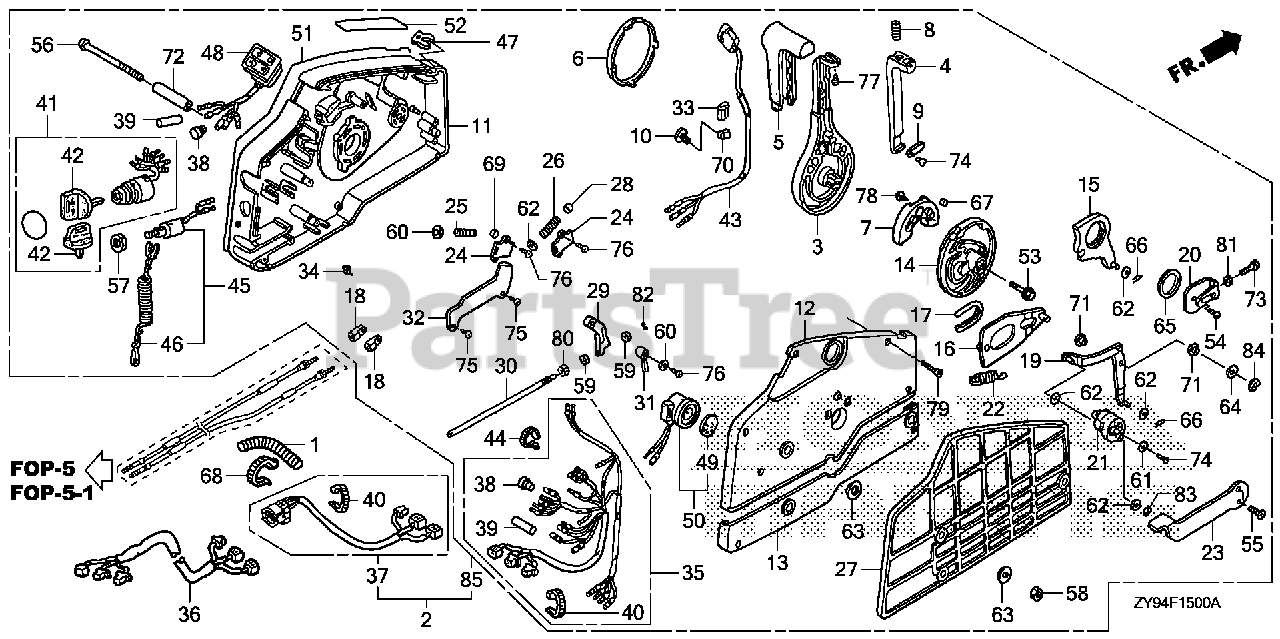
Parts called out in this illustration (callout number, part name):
1	TUBE, CORRUGATED (28MM)
2	BOX ASSY., REMOTE CONTROL (NHK MEC)
3	HANDLE, REMOTE CONTROL
4	LEVER, HANDLE LOCK
5	GRIP, REMOTE CONTROL HANDLE
6	CAP, HANDLE
7	BLOCK, NEUTRAL LOCK
8	SPRING, REMOTE CONTROL HANDLE
9	PLATE, LEVER SETTING
10	CLAMP, HARNESS
11	HOUSING, REMOTE CONTROL BOX (A)
12	HOUSING, REMOTE CONTROL BOX (B)
13	HOUSING, REMOTE CONTROL BOX (C )
14	WHEEL, CONTROL
15	ARM, SHIFT LINK
16	PLATE, SLIDING
17	COLLAR, SLIDING PLATE
18	PIVOT, SHIFT
19	ARM, LINK JOINT
20	BRACKET, LINK JOINT
21	WHEEL, ACCELERATOR
22	SPRING, ACCELERATOR WHEEL
23	LEVER, IDLE
24	PLATE, SPRING SETTING
25	SPRING, SHIFT CLICK
26	SPRING, CHOKE RETURN
27	SPACER, REMOTE CONTROL BOX
28	SPACER, CLICK SPRING
29	BLOCK, THROTTLE FRICTION
30	BOLT, FRICTION
31	SPACER, NEUTRAL SWITCH
32	CLAMP, POWER TILT CORD
33	PIPE, HARNESS GUIDE
34	SPACER, CABLE CLAMP
35	CABLE ASSY., REMOTE CONTROL (B) Use from Frame SN 1300029.
35	CABLE ASSY., REMOTE CONTROL (B) (FOR 4-LED)
36	CABLE ASSY., REMOTE CONTROL EXTENSION Use from Frame SN 1300029.
37	CABLE ASSY., SWITCH PANEL
37	CABLE ASSY., SWITCH PANEL (20FT) (NHK MEC)
37	CABLE ASSY., SWITCH PANEL (25FT) (NHK MEC)
37	CABLE ASSY., SWITCH PANEL (30FT) (NHK MEC)
37	CABLE ASSY., SWITCH PANEL (30FT) (FOR 4-LED)
38	PLUG, CONNECTOR (INNER) (TROLLING CONTROL)
39	PLUG, CONNECTOR (OUTER) (ENGINE NO.)
40	TIE, CABLE (NATURAL 2.4X92) Use up to Frame SN 1300359.
41	SWITCH ASSY., COMBINATION DUAL QTY = (2) (SINGLE)
41	SWITCH ASSY., COMBINATION (SINGLE) (DUAL)
42	KEY ASSY., COMBINATION SWITCH (35100-ZV5-003 ONLY) DUAL QTY = (4) (SINGLE)
43	SWITCH ASSY., POWER TRIM-TILT
44	BAND (BLACK 3.5X140)
45	SWITCH ASSY., EMERGENCY STOP
46	WIRE, EMERGENCY (SINGLE) (DUAL)
47	CLIP, EMERGENCY LOCK
48	LAMP ASSY., INDICATION (2-LED)
48	LAMP ASSY., INDICATION
49	PLATE, TURN SIGNAL BUZZER DUAL QTY = (2) (SINGLE)
50	BUZZER, WARNING DUAL QTY = (2) (SINGLE)
51	PLATE, REMOTE CONTROL (CAUTION=SILVER)
51	PLATE, REMOTE CONTROL (CAUTION PICT=SILVER) (FOR 4-LED)
51	PLATE, REMOTE CONTROL (COUTION COLOR=RED & YELLOW)
52	MARK, FAST IDLE
53	BOLT, FLANGE (8X35) Use from Frame SN 4800713.
54	SCREW, PAN (6X10)
55	SCREW, FLAT (5X12) Use from Frame SN 4800713.
56	SCREW (6X95)
57	NUT, HEX. (16MM) DUAL QTY = (2) (SINGLE)
58	NUT, HEX. (6MM)
59	WASHER, PLAIN (4MM) Use from Frame SN 4800713.
60	WASHER, PLAIN (5MM)
61	WASHER, PLAIN (5MM)
62	WASHER, PLAIN (6MM) Use from Frame SN 4800713.
63	WASHER (6MM)
64	WASHER, PLAIN (8MM) Use from Frame SN 4800713.
65	WASHER (28MM)
66	PIN, LOCK (6MM)
67	PIN (6X6)
68	BAND, SELF-LOCK Use from Frame SN 3000253.
69	ROLLER, CLICK
70	CLIP, WIRE HARNESS (6.3MM)
71	COLLAR, LINK JOINT
72	COLLAR, DISTANCE (6X10X43.5)
73	BOLT, HEX. (5X16)
74	SCREW, PAN (5X10)
75	SCREW, TAPPING (5X8) (FOR SILVER MUFFLER)
76	SCREW, TAPPING (5X10)
77	SCREW, TAPPING (5X12)
78	SCREW, TAPPING (6X16)
79	SCREW, TAPPING (5X25)
80	NUT, HEX. (6MM)
81	NUT, HEX. (5MM)
82	E-RING (3MM)
83	E-RING (4MM)
84	E-RING (7MM)
85	BOX ASSY., REMOTE CONTROL (TROLLING CONTROL)(NHK MEC)
